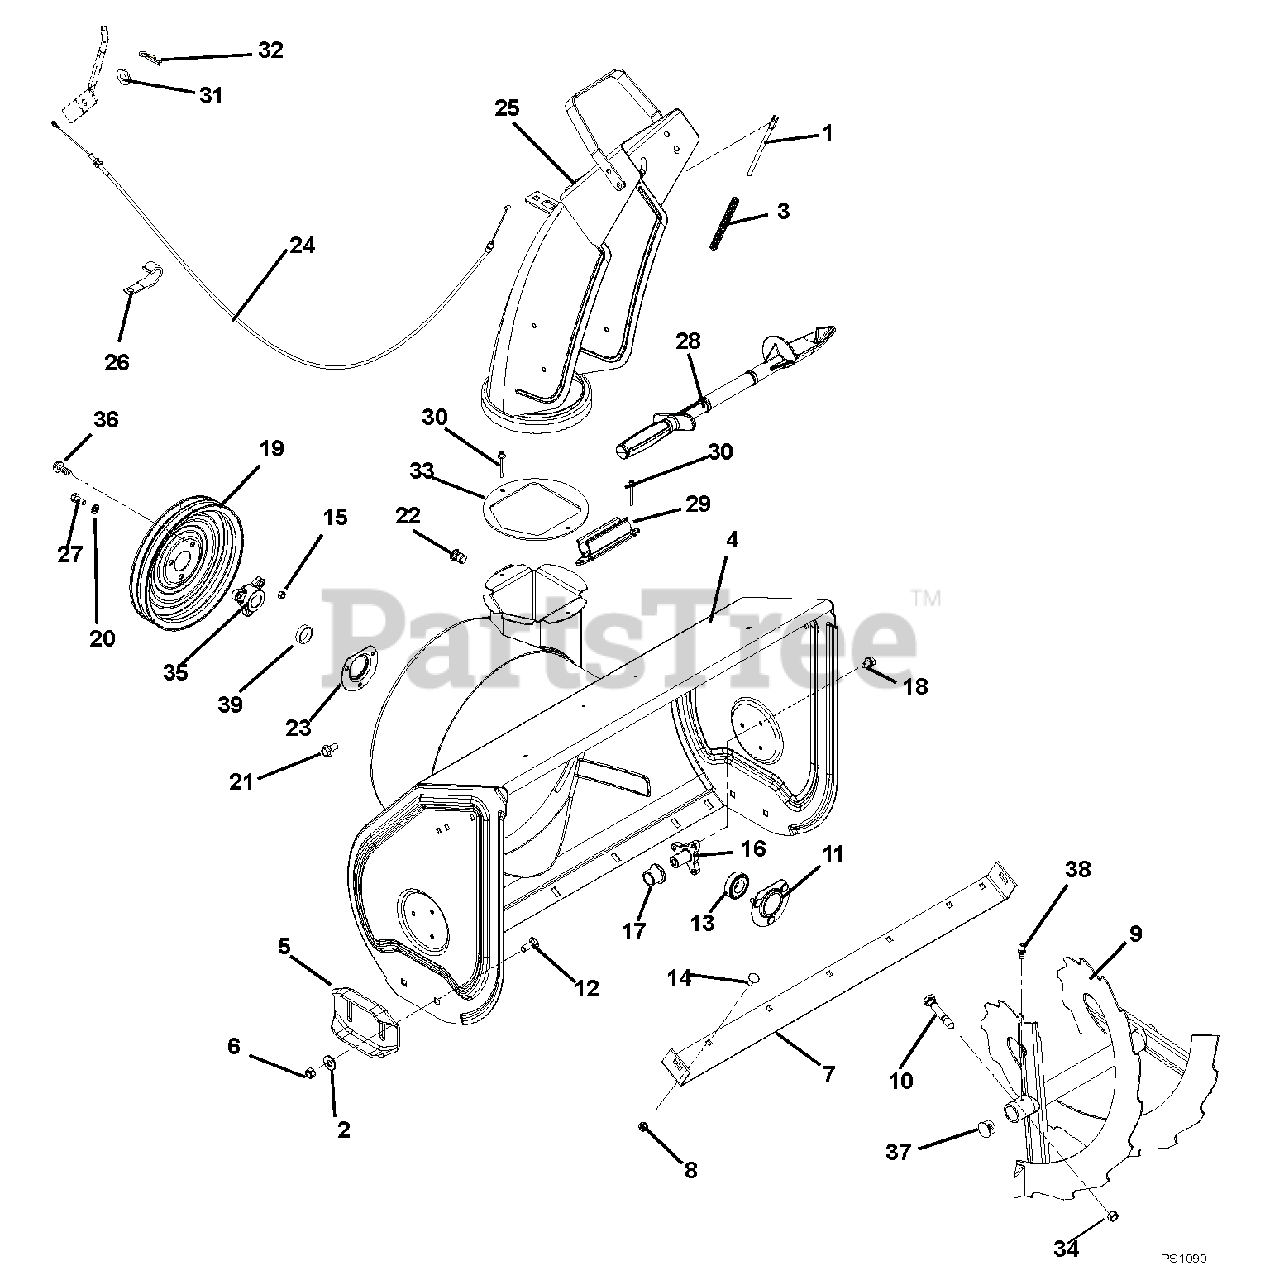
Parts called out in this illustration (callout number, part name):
1	ROD, DEFLECTOR CAP
2	@WSHR-FL-STL.438X1.00X.083 YWZ
3	SG-COMP .08X.40X6.50 14#/IN
4	BLOWER HOUSING W/DECAL 24"
4	BLOWER HOUSING, 28"
4	BLOWER HOUSING W/DECAL 30"
5	SKID SHOE, REVERSIBLE - ORANGE
6	@NUT-LK-CTR .38-16 YWZC
7	BLADE, SCRAPER-24"
7	BLADE, SCRAPER - 28"
7	BLADE, SCRAPER-30"
8	@NUT-LK-TOP-FLG .31-18 YWZC
9	RAKE, LH W/ZERK - 24"
9	RAKE, RH W/ZERK - 24"
9	RAKE, LH W/ZERK - 28"
9	RAKE, RH W/ZERK - 28"
9	RAKE, LH W/ZERK - 30"
9	RAKE, RH W/ZERK - 30"
10	SHEAR BOLT SERVICE ASSEMBLY
11	BEARING FLANGE
12	@BLT-RDHDSHSQNK.38-16X1.0 G5YZ
13	BRG-BALL .876 X 1.750 X .50
13	BRG-BALL .876X1.75X.50 RSTFP
14	BLT,RDSHHDSQSHNK .31-18X.62 YZ
15	@NUT-LK-CTR .25-20 YWZC
16	SUPPORT, RAKE BUSHING
17	BSHG-FLG, NY.778 ID X 1.018 OD
18	SCR-TAP .25-20X.50 HWH TR YWZ
19	PULLEY, SPIN FORM DUAL GROOVE
20	WSHR-LK .312X.097 HVY YWZC
21	SCR-TAP.31-18X.50 HWH TR YWZ
22	NUT, THREADED INSERT .38-16
23	BEARING FLANGE
24	CABLE, DEFLECTOR-COATED
24	CABLE, DEFLECTOR - SMALL DLX
25	CHUTE, DISCHARGE-W/DEFLECTOR
25	CHUTE, DISCHARGE W/CAP & DECAL
26	J-CLAMP
27	BLT-HEX .31-24X.75 YWZC GR5
28	DEVICE, SNOW CLEAN OUT
29	MOUNT, SNOW CLEAN OUT
30	RVT-POP .187 YZ
31	@WSHR-FL-STL.281X.62X.065 YWZC
32	PIN-HAIR INT .06X.18X.77
33	BAFFLE, DISCHARGE NECK
34	@NUT-LK-CTR .31-18 YWZC
35	PULLEY HUB, D-BORE .87 DELUXE
36	@SCR-TAP .31-18X.50 HWH TR YWZ
37	PLUG
38	ZERK,FITTING .25X.125 DRIVE IN
39	BSHG-SPCR .895IDX1.065ODX.29
